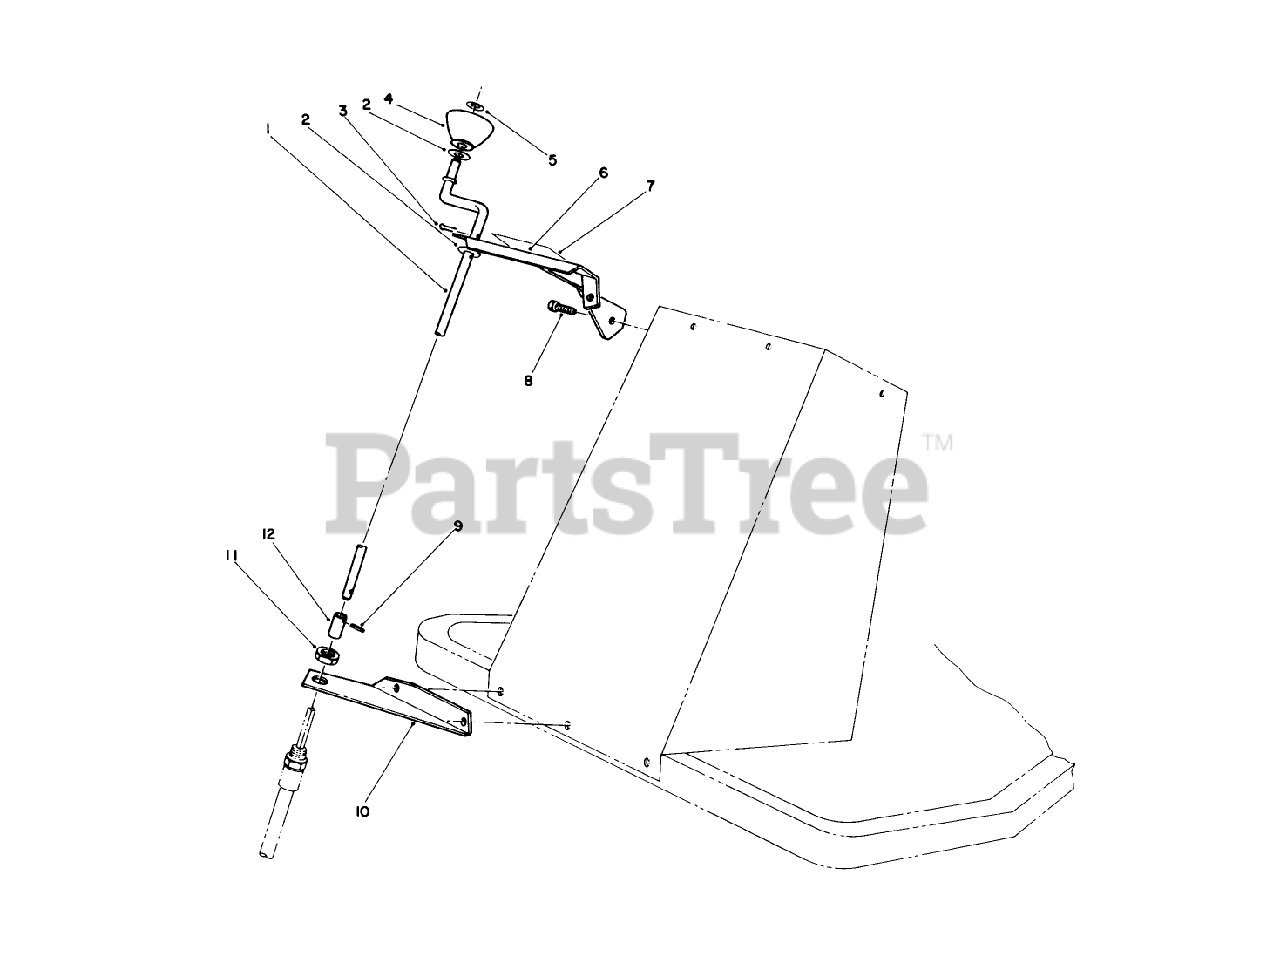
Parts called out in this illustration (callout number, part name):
1	CHUTE CONTROL ROD
2	WASHER-FLAT
3	PIN-COTTER
4	KNOB-CHUTE
5	NUT-PUSH
6	TOP BRKT R
7	Decal-Chute Rotation
8	SCREW-HH
9	PIN-SPRING
10	BOTTOM BRKT R
11	LOCKNUT
12	COUPLER
